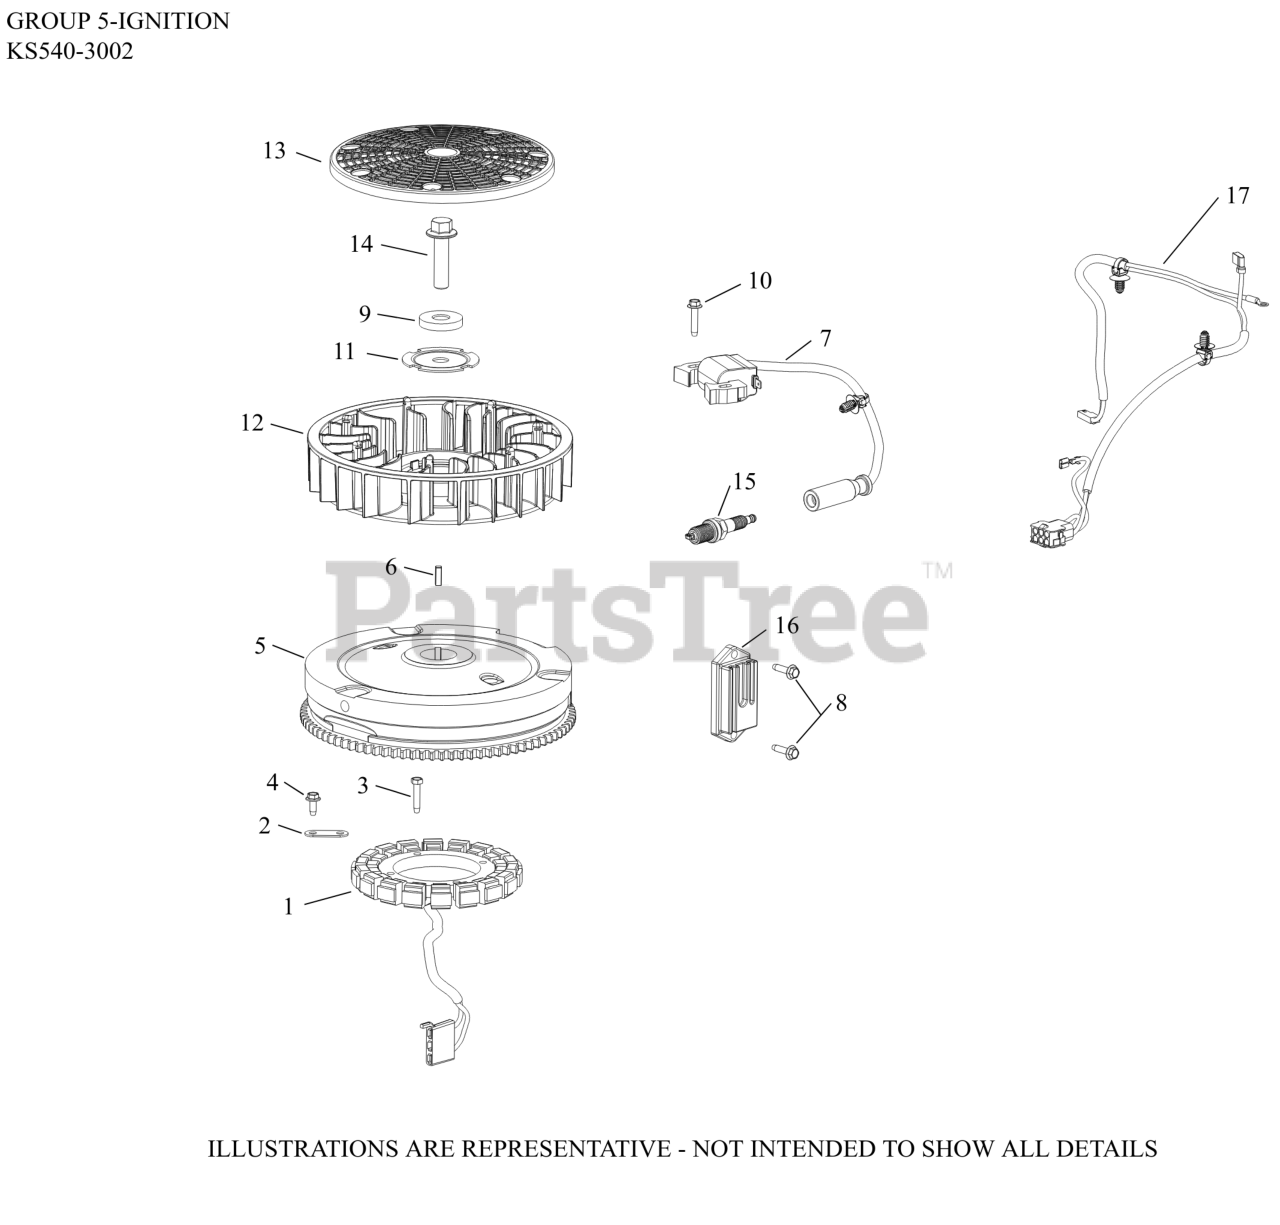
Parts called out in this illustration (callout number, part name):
1	STATOR ASSY, 12A
2	CLIP, STATOR WIRE
3	SCREW, THREAD FORMING
4	SCREW, FLG THD FRM M5X0.8X13
5	FLYWHEEL, ASSY
6	KEY, SQUARE
7	MODULE, INDUCTIVE IGNITION COIL
8	SCREW, THD FRM-USE 25 086 473-S
9	WASHER, FLAT
10	SCREW, THREAD FORMING
11	PLATE, FAN MOUNTING
13	SCREEN, GRASS
14	SCREW, HEX FLANGE
15	PLUG SPARK 12MM RFI
16	REGULATOR/RECTIFIER 12/15A HALF-WAVE STD
17	HARNESS, WIRING NON-OSU, NON MTD
